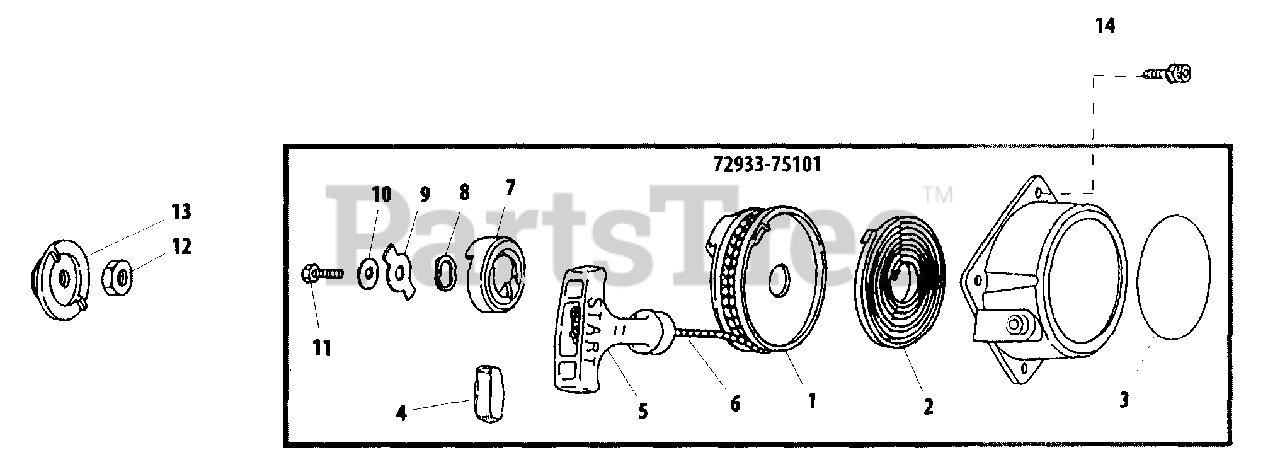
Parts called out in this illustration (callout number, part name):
1	REEL, ROPE
2	SPRING, RECOIL
3	LABEL, RECOIL STARTER
4	RETAINER, ROPE
5	HANDLE
6	ROPE, STARTER
7	RATCHET
8	WASHER, WAVE
9	RETAINER
10	WASHER 5 MM
11	SCREW 5 MM
12	NUT M8×1
13	PULLEY, STARTER
14	BOLT M4×12
72933-75101	STARTER ASSY, RECOIL
